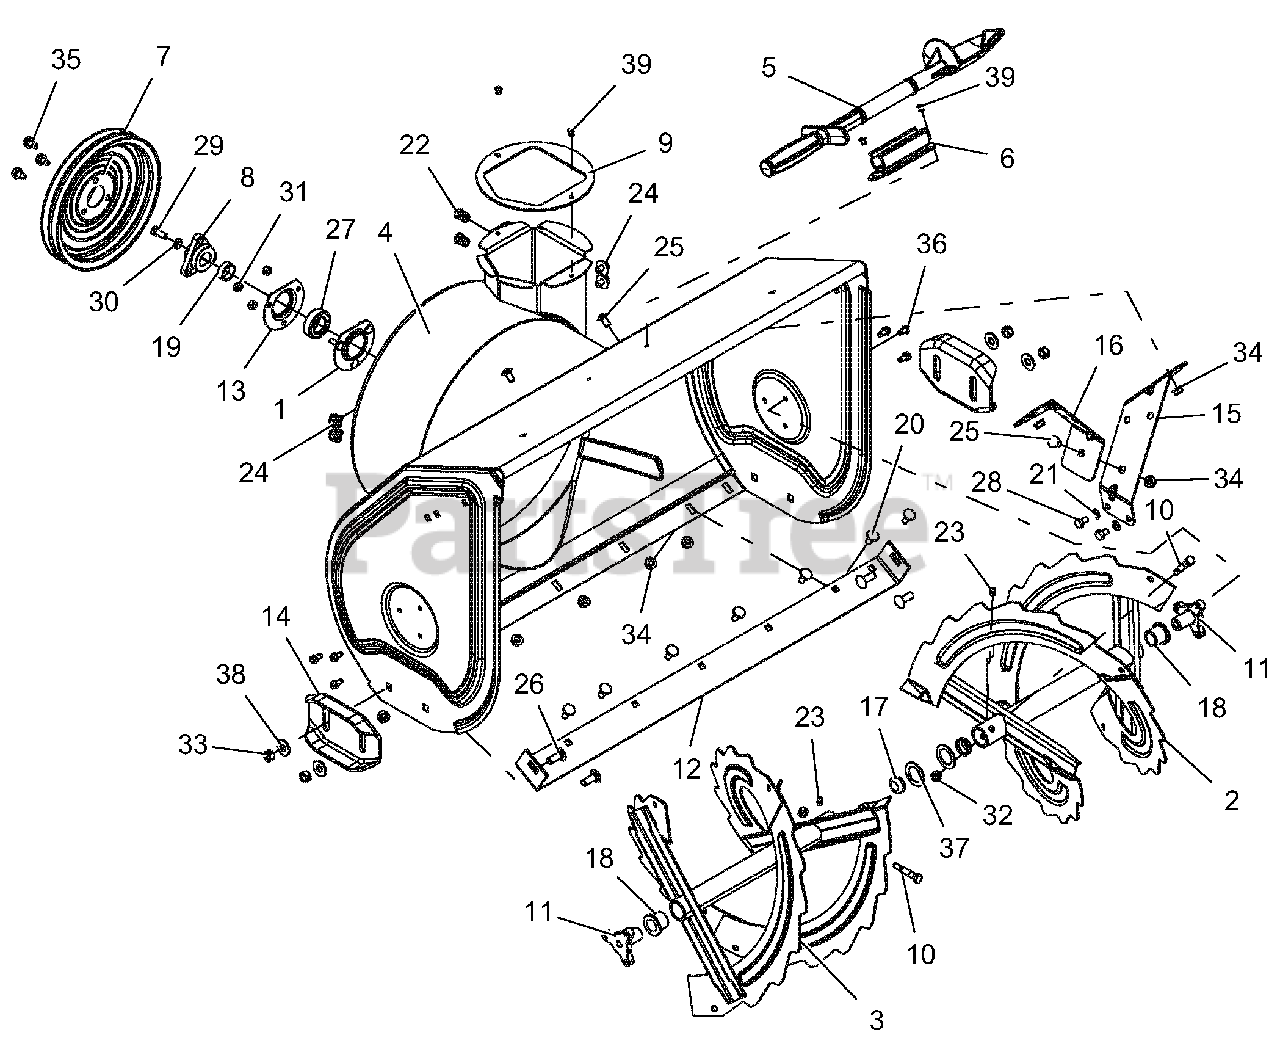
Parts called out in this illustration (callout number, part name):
1	BEARING FLANGE
2	RAKE, LEFT HAND-30" DELUXE
3	RAKE, RIGHT HAND-30" DELUXE
4	HOUSING, BLOWER - 30" DELUXE
5	DEVICE, SNOW CLEAN OUT
6	MOUNT, SNOW CLEAN OUT
7	PULLEY, SPIN FORM DUAL GROOVE
8	PULLEY HUB, D-BORE .87 DELUXE
9	BAFFLE, DISCHARGE NECK
10	SHEAR BOLT SERVICE ASSEMBLY
11	SUPPORT, RAKE BUSHING
12	BLADE, SCRAPER-30"
13	BEARING FLANGE
14	SKID SHOE, REVERSIBLE - ORANGE
15	BRACKET, GEARCASE SUPPORT - LH
16	BRACKET, GEARCASE SUPPORT - RH
17	PLUG, RAKE TUBE
18	BSHG-FLG, NY.778 ID X 1.018 OD
19	BSHG-SPCR .895IDX1.065ODX.353
20	BOLT, MODIFIED HEAD CARRIAGE
21	@WSHR-LK-EXT.326X.599X.031YWZC
22	NUT, THREADED INSERT .38-16
23	ZERK,FITTING .25X.125 DRIVE IN
24	SCR-TAP.31-18X.50 HWH TR YWZ
25	BLT-RDHDSQSHNK.31-18X.62 YZ-LK
26	@BLT-RDHDSHSQNK.38-16X1.0 G5YZ
27	BRG-BALL .876 X 1.750 X .50
28	@BLT-HEX .31-18X.50 GR5 YWZC
29	BLT-HEX .31-24X.75 YWZC GR5
30	WSHR-LK .312X.097 HVY YWZC
31	@NUT-LK-CTR .25-20 YWZC
32	NUT-LK-CTR .31-18 YWZC
33	@NUT-LK-CTR .38-16 YWZC
34	@NUT-LK-TOP-FLG .31-18 YWZC
35	@SCR-TAP .31-18X.50 HWH TR YWZ
36	SCR-TAP .25-20X.50 HWH TR YWZ
37	WSHR-FL-STL 1.010X1.505X.062YZ
38	@WSHR-FL-STL.438X1.00X.083 YWZ
39	RVT-POP .187 YZ
